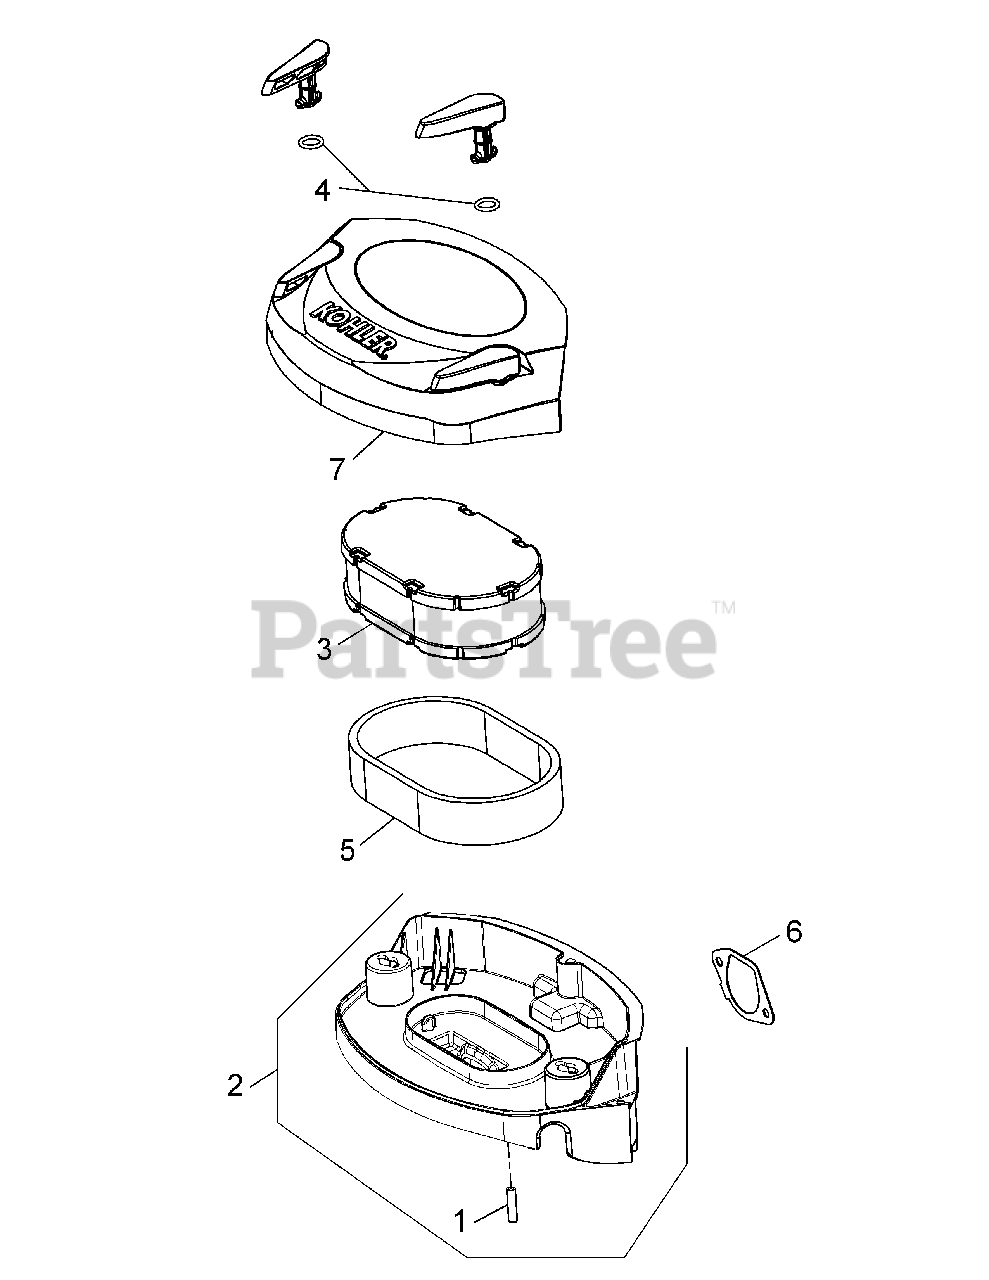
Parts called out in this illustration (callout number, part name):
2	Air Cleaner Base Assembly
3	Air Filter Element
5	Pre-Cleaner Element
6	Air Cleaner Base Gasket
7	Air Cleaner Cover Assembly
